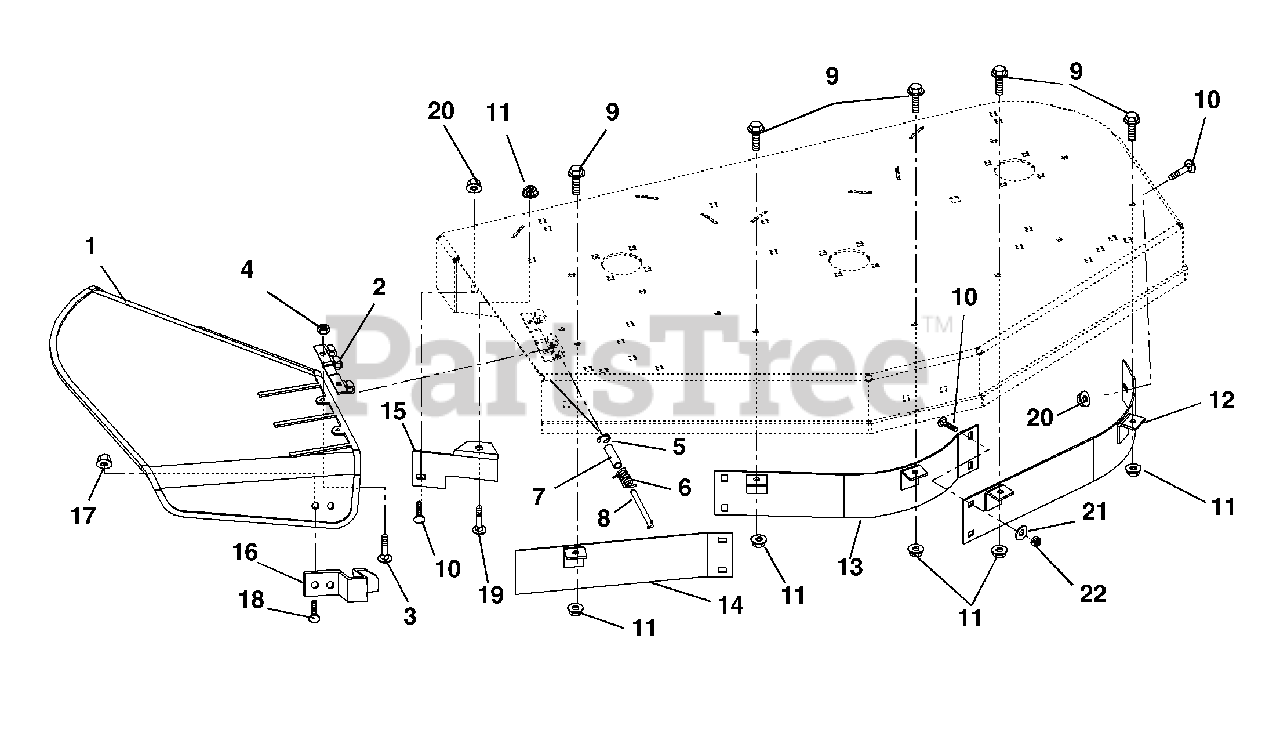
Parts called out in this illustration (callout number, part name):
1	DEFLECTOR, CHUTE
2	HINGE PLATE
3	@BLT-RDHDSQNK .25-20X.75 G5YZ
4	@NUT-SPNLK-FLG .25-20 YWZC
5	RG-RTNG-EXT .312X.025
6	SG-TORS .095X.50X 1.0
7	BSHG-SLV .334 X .502 X 1.437
9	BLT SERHFWH .31-18X.62 GR5BKZC
10	@BLT-RHDSSQNK .31-18X.62 G5YZ
11	@NUT-LK-NYL-FLG .31-18 YWZC
12	BAFFLE - LEFT FRONT - 40"
13	BAFFLE - CENTER FRONT - 40"
14	BAFFLE - RIGHT FRONT - 40"
15	DEFLECTOR-40"
16	FLAT SPRING
17	@NUT-LK-TOP-FLG .25-20 YWZC
18	@BLT-RDHDSQNK .25-20X.50 G5YZ
19	@BLT-RDHDSQNK .38-16X.75 G5YZ
20	@NUT-LK-NYL-FLG .31-18 YWZC
21	@WSHR-FL-STL.344X.688X.065YWZC
22	@NUT-LK-NYL .312-18 YWZC
